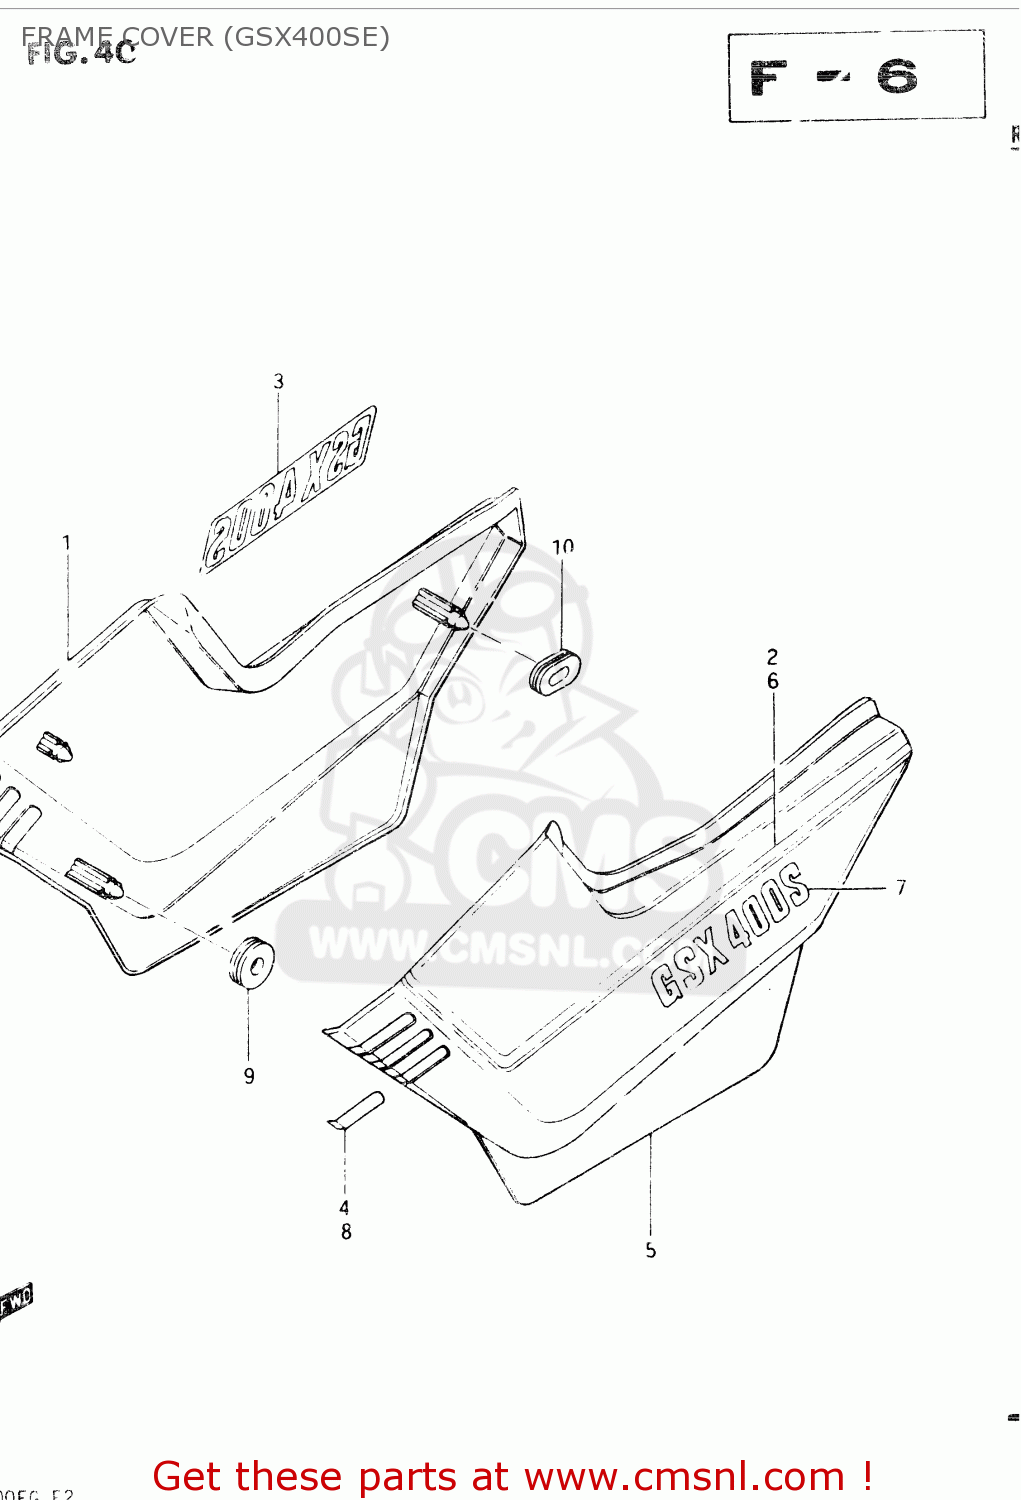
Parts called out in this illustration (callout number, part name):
1	COVER SET, FRAME RH
2	TAPE SET, FRAME COVER RH
3	EMBLEM
4	LABEL,FRAME COVER DENT,R
5	COVER SET, FRAME LH
6	TAPE SET, FRAME COVER LH
7	EMBLEM
8	LABEL,FRAME COVER DENT
9	CUSHION
10	CUSHION
